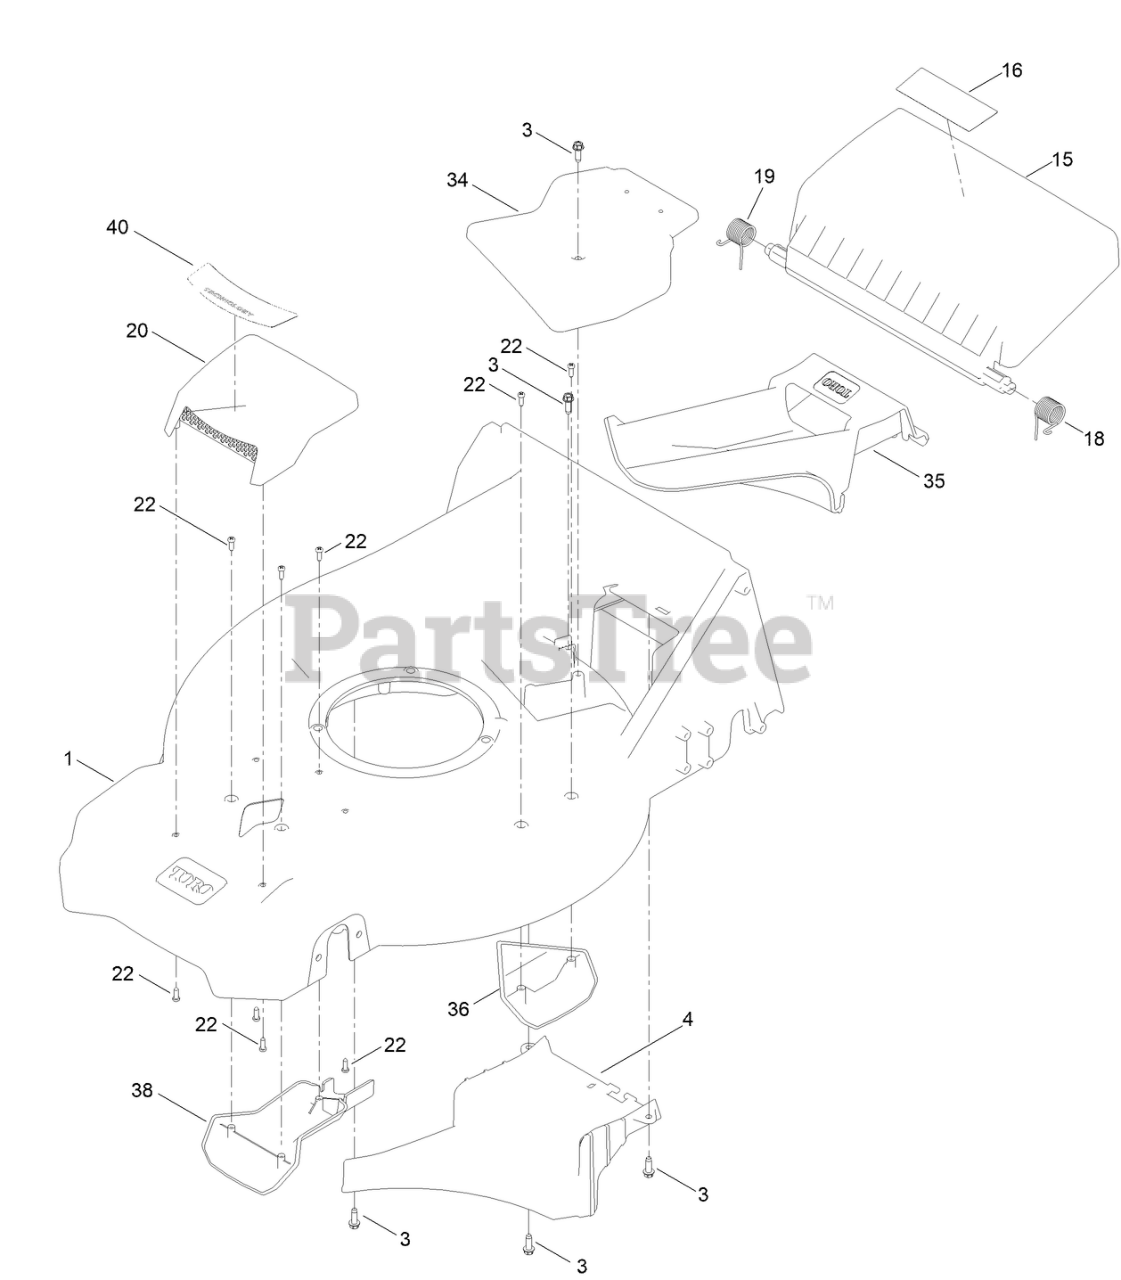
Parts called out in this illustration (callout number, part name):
1	HOUSING ASM
3	SCREW-HWHTF
4	RAMP-DISCHARGE
15	DOOR-REAR
16	DECAL-WARNING
18	SPRING-TORSION, LH
19	SPRING-TORSION, RH
20	ASM-COVER, TOP INTAKE
22	SCREW-PLASTIC, PPH
34	COVER-BELT, TOP
35	PLUG-MULCH
36	KICKER-HOUSING
38	COVER-INTAKE, BOTTOM
40	DECAL-COVER, INTAKE
